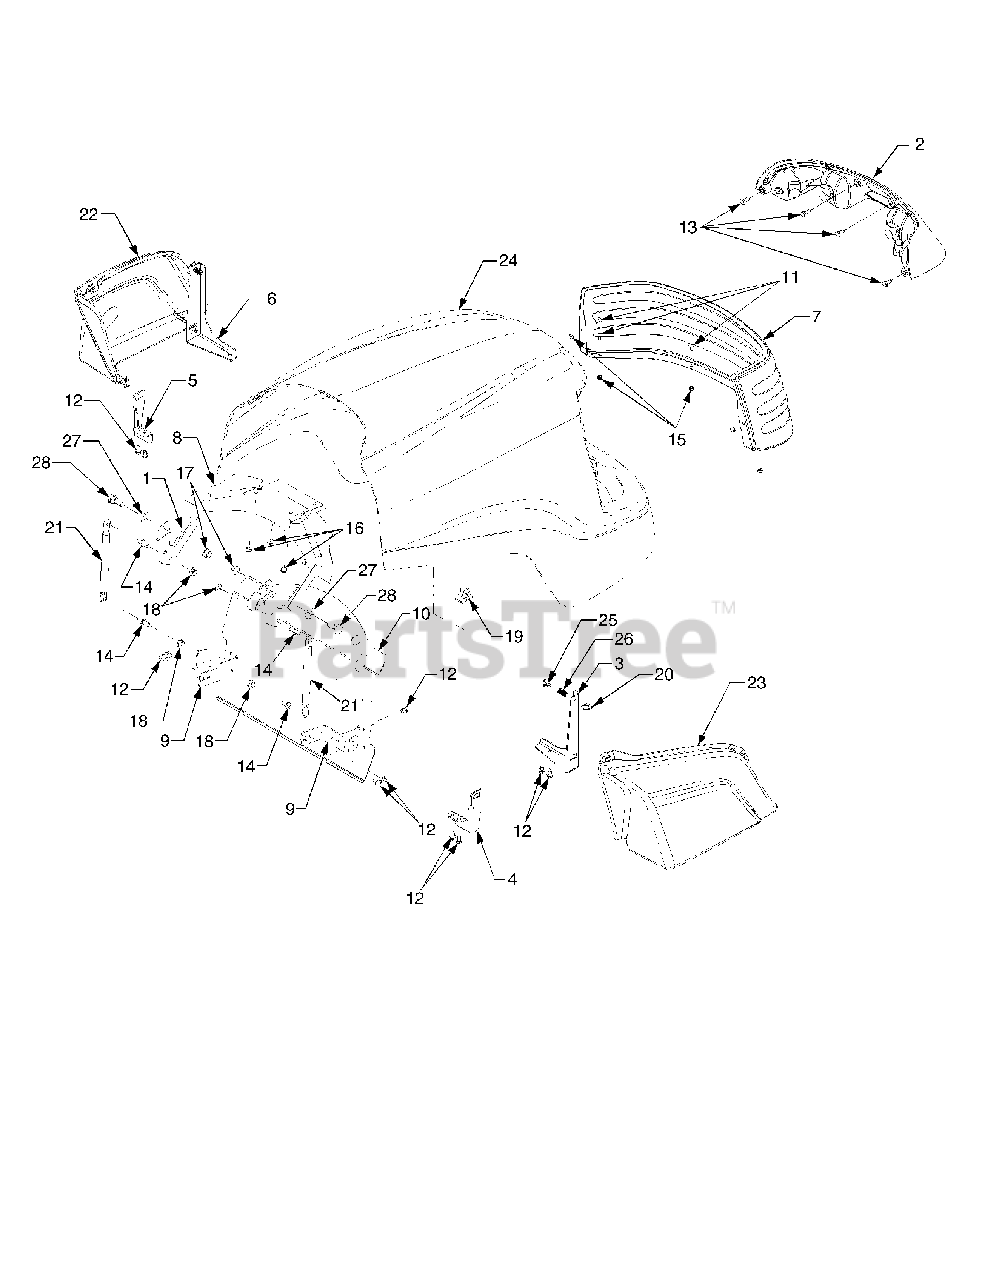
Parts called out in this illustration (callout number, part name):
1	Hinge Assembly, Hood
2	Headlight Assembly
3	Bracket, Side Panel Mtg. RH
4	Bracket, Side Panel Mtg. RH Rear
5	Bracket, Side Panel Mtg. LH Rear
6	Bracket, Side Panel Mtg. LH
10	Shield, Lower Heat
11	Screw, Truss Hd, 10-24 x .5
12	Screw, Hex Wash Hd Tapp 1/4-20 x .5
13	Screw, Hex Wash. Hd.1/4-20 x .62 GR5
14	Stud, Cylinder, 5/16-18 Thrd
15	Nut, Hex Sems, 10-24
16	Nut, Hex Nylon Insert Lock, 1/4-20
17	Nut, Hex Flange Lock, 3/8-16
18	Nut, Hex Flange Lock, 5/16-18
19	Clip, Retaining
20	Latch, 1/4 Turn Panel
21	Cylinder, Gas Spring
22	Panel, Side LH
23	Panel, Side RH
24	Hood, Service Kit
24	Hood
24	Graphic, Hood RH
24	Graphic, Hood LH
24	Graphic, Model 6284 LH
24	Graphic, Model 6284 RH
24	Graphic, Cat
25	Clip, Spring
26	Spring, Compression
27	Washer, Flat, .51 x 1.0 x .060
28	Screw, Shoulder, .5 x .27 Lg 3/8-16
